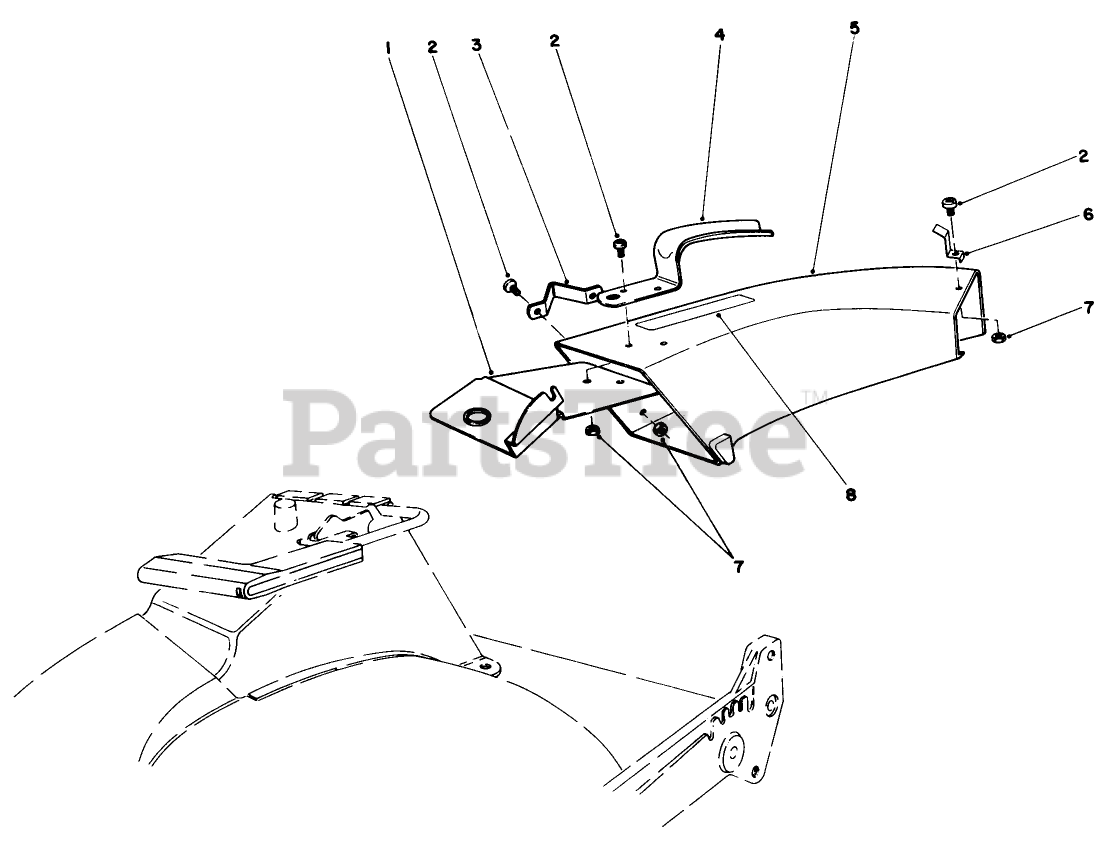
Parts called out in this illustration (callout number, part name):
2	10-24 X 5/8 PAN HD MS
4	CHUTE HANDLE
5	ORDER 59168 W.G.#
7	NUT-LOCK, NI
